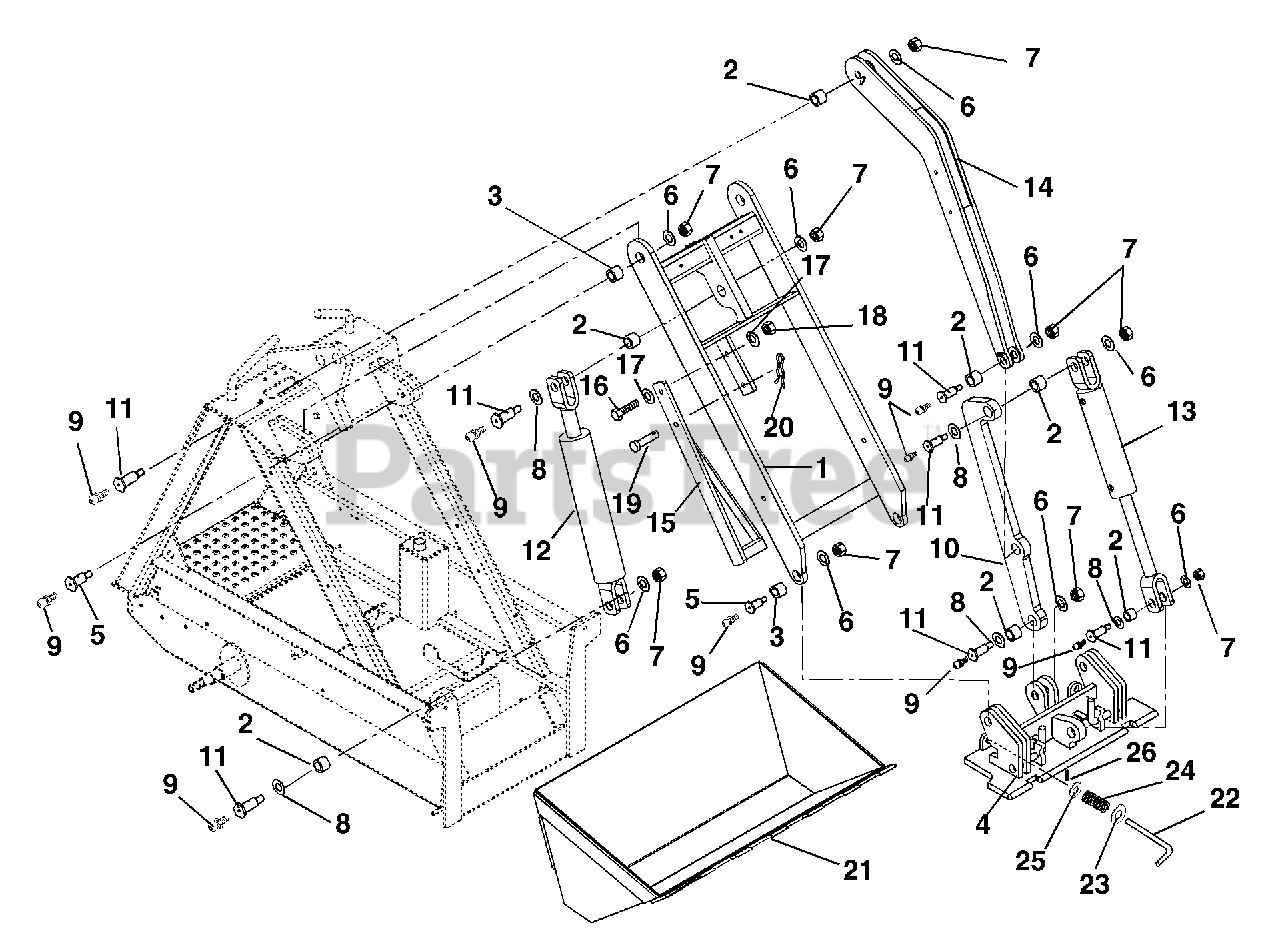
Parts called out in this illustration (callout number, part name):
1	Weldment, Boom Assembly
2	Bushing-1.00 x 1.25 x 25.65 MM
3	Bushing-1.00 x 1.25 x 16.125 MM
4	Plate, Attachment
5	Pin-Linkage "A" 1.50 Hex
6	Washer-Flat-Steel .656 x 1.31 x .095
7	Nut-Locking-Nylon M16-1.5
8	Washer-Flat-Steel 1.01 x 1.50 x .062
9	Fitting-Lube .25-28 x .256
10	Arm-Tilt
11	Pin-Linkage "B" 1.50 Hex
12	Cylinder-Lift
12	Seal, Replacement
13	Cylinder-Crowd
13	Seal, Replacement
14	Arm-Leveler
15	Bracket-Cylinder Lock Weldment
16	Bolt-Hex M12-1.75 x 45
17	Washer-Flat-Steel .531 x 1.06 x .095
18	Nut-Locking-Nylon M12-1.75
19	Pin-Clevis .438 x 1.50
20	Pin-Hair Internal .15 x 2.937
22	Pin, Locking
23	Washer-Flat-Steel .755 x 1.38 x .062
24	Spring-Compression .08 x .91 x 3.38
25	Washer-Flat-Steel .63 x 1.005 x .062
26	Pin-Roll .125 x 1.00
